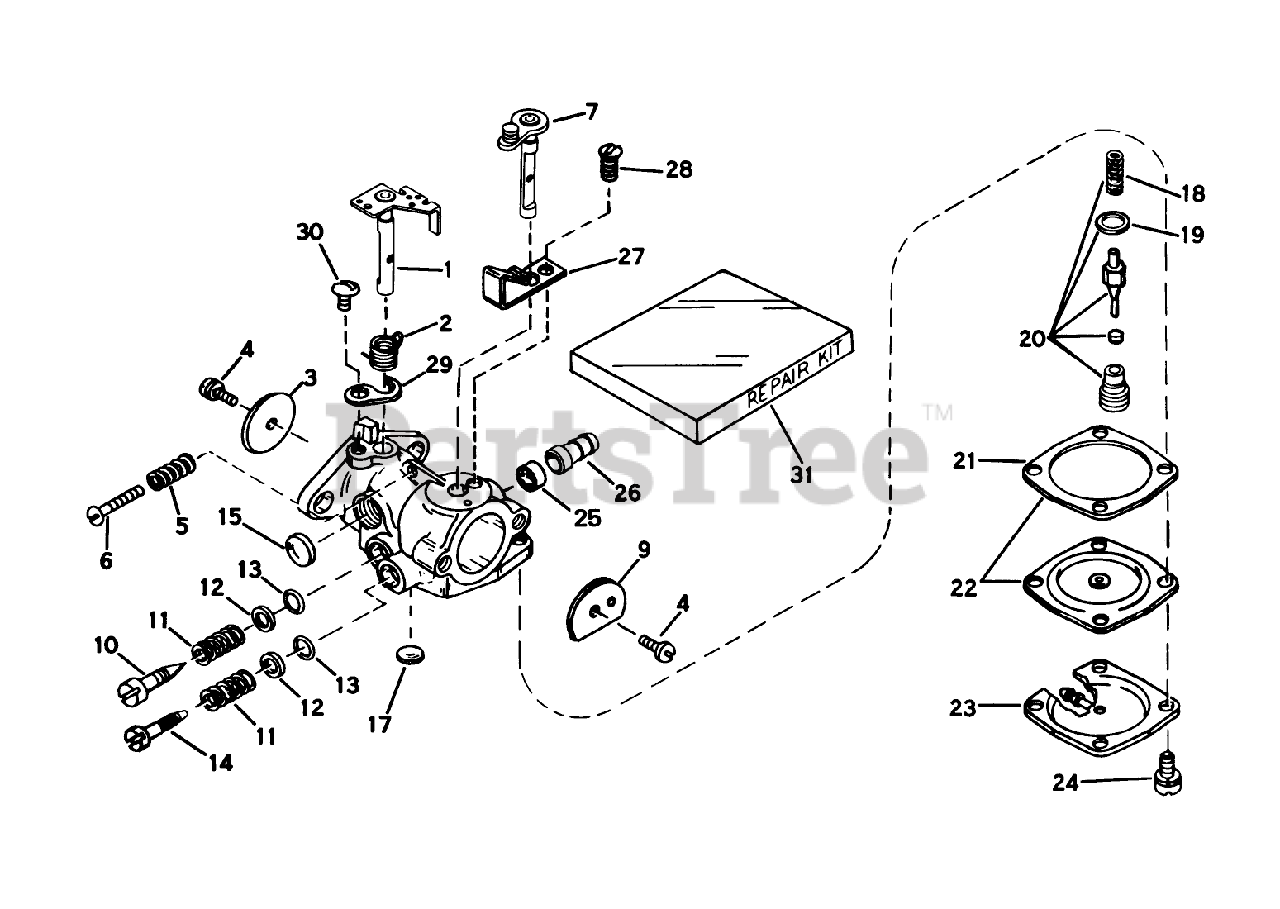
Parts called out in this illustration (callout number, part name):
1	Shaft Lever Assy., Throttle
2	Spring Return
3	Shutter, Throttle
4	Screw-Shutter
5	Spring-Tension
6	Screw-Throttle Crack Screw / Idle Speed
7	Shaft Lever Assy., Choke
10	Screw-Idle Adjustment
11	Spring
12	Washer
13	ORing
14	Screw Main Adjustment
15	Plug-Welch, Idle Mixture Well
17	Plug Welch
18	Spring-Valve
19	Gasket-Valve Seat
20	Inlet Needle, Seat, Spring Gasket Assy. (Incl. Nos. 18 19)
21	Gasket-Diaphragm
22	Diaphragm Ass. (Incl. No. 21)
23	Cover, Diaphragm
24	Screw, Diaphragm Cover
25	Valve Check
26	Fitting, Fuel inlet
27	Spring, Detent
28	Screw Detent spring
29	Retainer, Throttle Shaft
30	Screw Detent spring
31	Repair Kit
